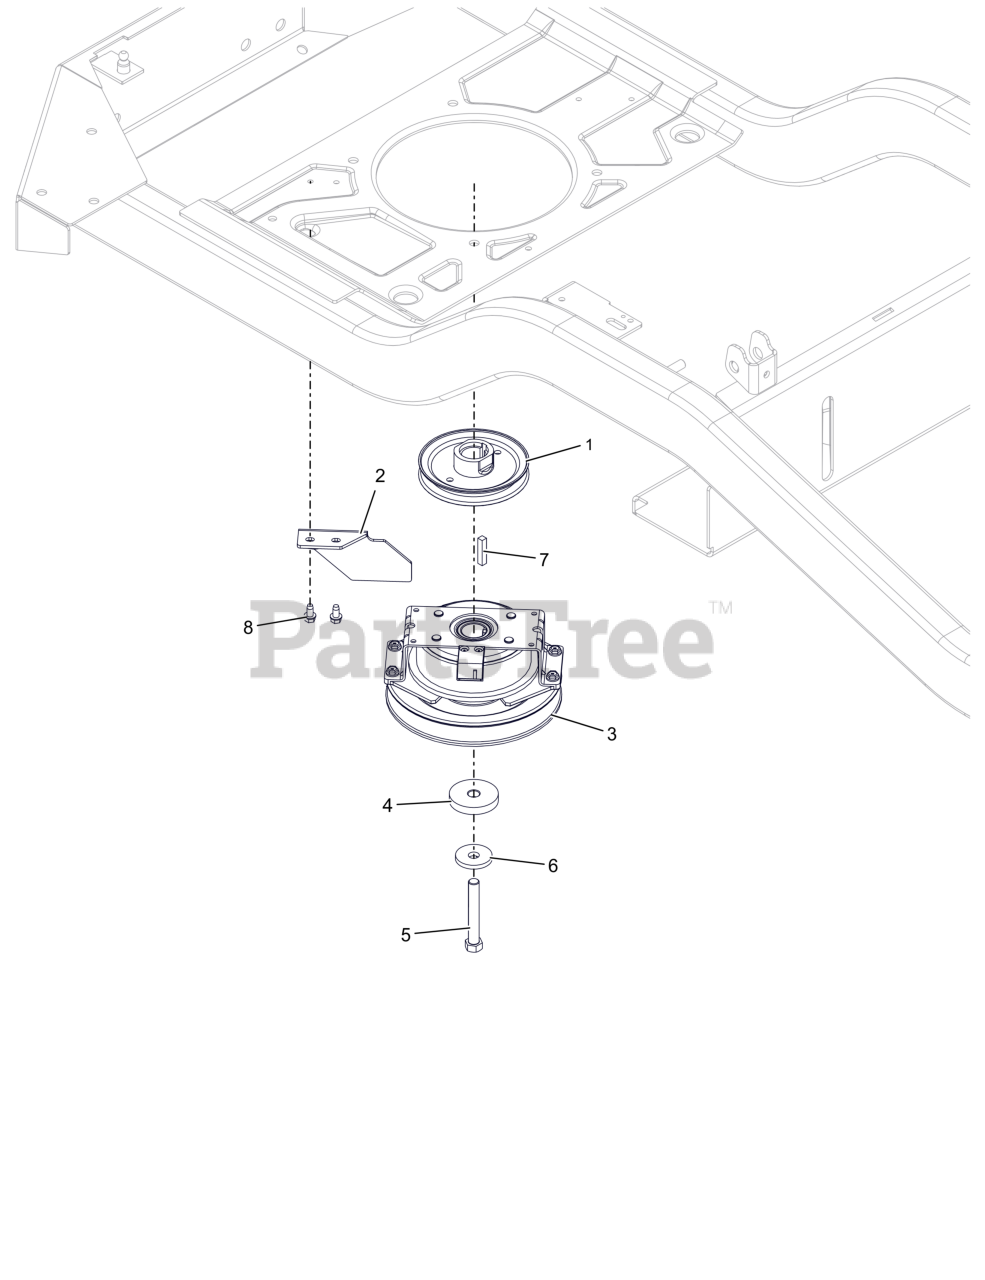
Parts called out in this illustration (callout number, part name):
1	WLDMT,PULLEY-4.50ODX1.003
2	BRKT, CLUTCH STOP HD
3	CLUTCH, OGURA DBL SPRG
4	SPACER, .474/.459X2.00X.350
5	BLT, HEX .44-20X3.00 G8 ZCC NT
6	WASHER, 7/16" SPRING DISK
7	KEY-SQ .25 X 1.25 X .25 SAE
8	SCR-TAP .25-20X.50 HWH ZCC
